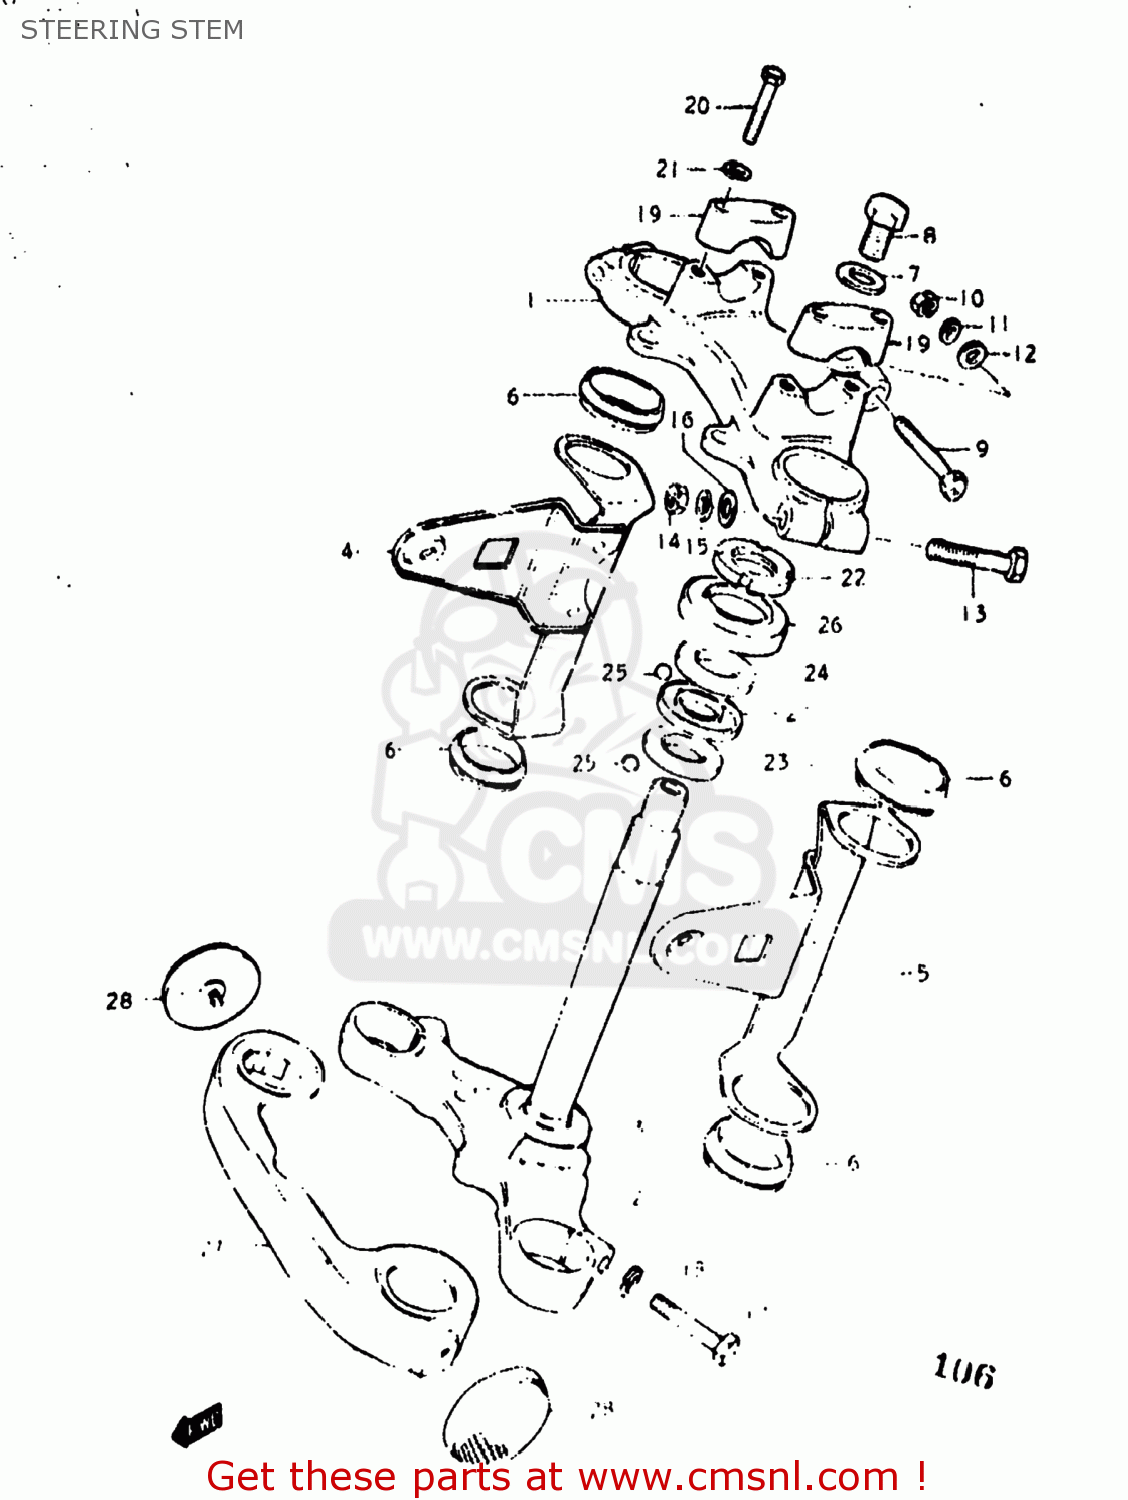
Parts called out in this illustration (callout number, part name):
1	HEAD,STEERING STEM
2	STEM,STEERING
3	RACE,STEERING OUTER LWR
4	BRACKET,HEADLAMP,RIGHT
5	BRACKET,HEADLAMP,LEFT
6	CUSHION,HEADLAMP BRACKET
7	WASHER
8	BOLT(12X20)
9	Bolt 8X50
10	NUT
11	LOCK WASHER
12	WASHER
13	BOLT 10X55
14	NUT
15	LOCK WASHER
16	WASHER
17	Bolt 10X40
18	LOCK WASHER
19	HOLDER,HANDLEBAR
20	Bolt
21	LOCK WASHER
22	NUT,STEERING STEM(25X44X10)
23	LACE,STEERING INNER LWR
24	LACE,STEERING OUTER UPR
25	BALL
26	DUST SEAL,STEERING UPR
27	COVER,FRONT FORK
28	REFLEX REFLECTOR,FR
